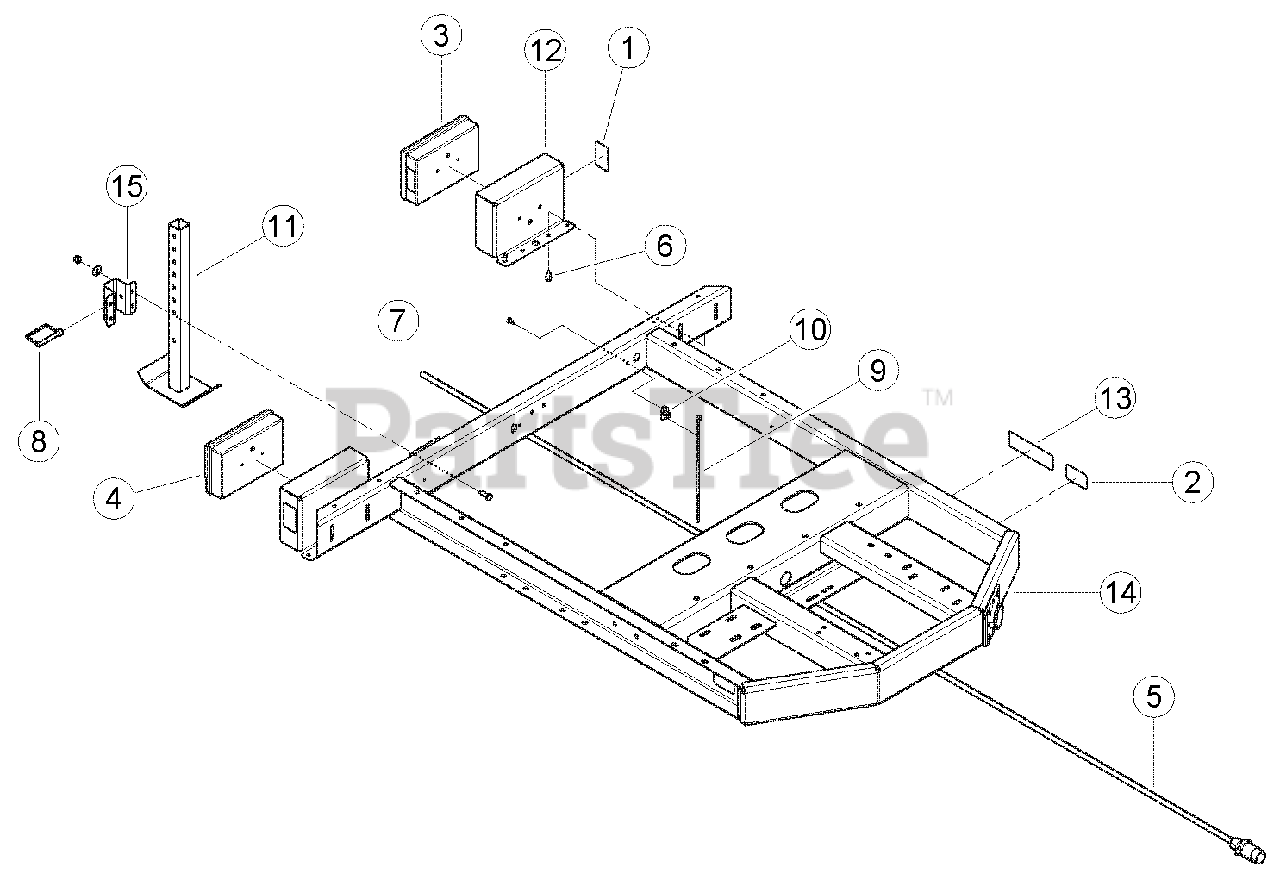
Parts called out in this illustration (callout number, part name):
1	REFLECTOR, WIDE ANGLE RED
2	REFLECTOR, WIDE ANGLE AMBER
3	LIGHT, TAIL RH
4	LIGHT, TAIL LH
5	HARNESS, TRAILER LIGHTING
6	SCREW, 11/32 X 7/8 HWH AB THREAD ZP
7	RIVET, AL BLIND 1/4 X 3/4 DOME HEAD
8	PIN, 3/8 X 2-3/4 SNAP
9	STRAP, 11 IN. BLACK TIE
10	CLAMP, CABLE MOUNT
11	WELDMENT, REAR STABILIZER
12	BRACKET, TAIL LIGHT
13	TAG, VIN
14	WELDMENT, CHIPPER TRAILER
15	GUIDE, TRAILER SUPPORT [WAS 76652-12]
